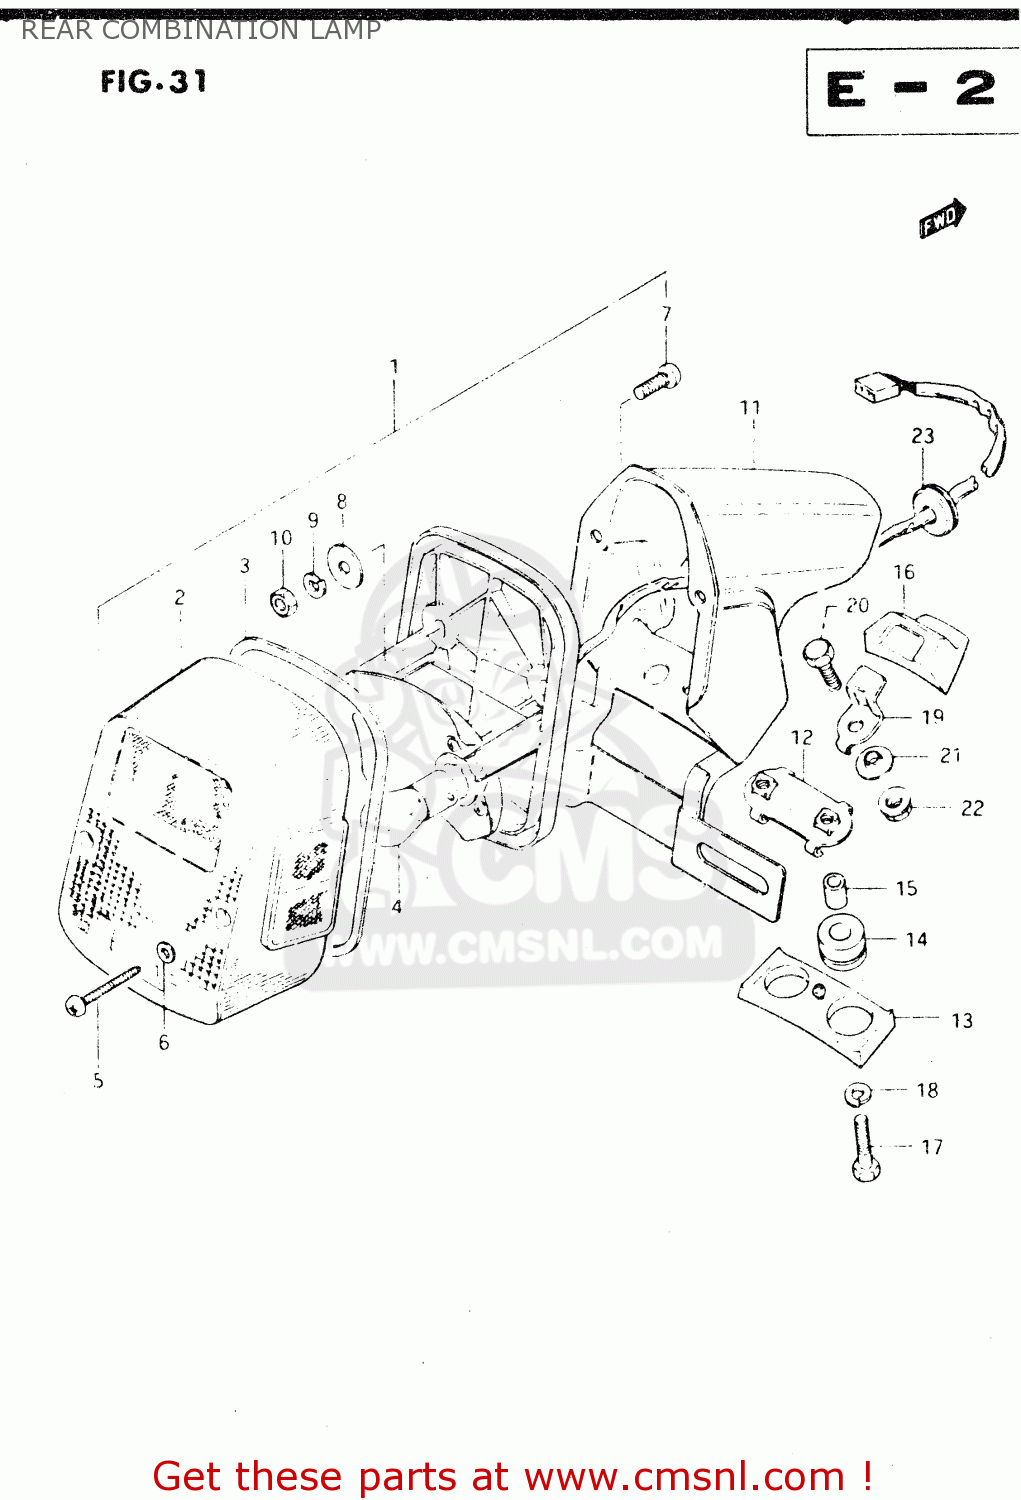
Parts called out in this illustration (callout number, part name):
1	LAMP UNIT, REAR COMBINATION
2	LENS
3	GASKET (NAS)
4	BULB(6V17/5.3W,STANLEY,A4813)
5	SCREW TAPP.
6	GASKET (NAS)
7	SCREW
8	WASHER,REAR COMBINATION LAMP
9	LOCK WASHER
10	NUT
11	BRACKET UNIT,TAIL LAMP
12	PLATE
13	CUSHION
14	CUSHION
15	SPACER
16	CUSHION,REAR COMBINATION LAMP
17	BOLT
18	LOCK WASHER
19	PLATE,RR COMBINATION LAMP
20	BOLT, UPPER
21	WASHER,LOCK
22	NUT
23	GROMMET
